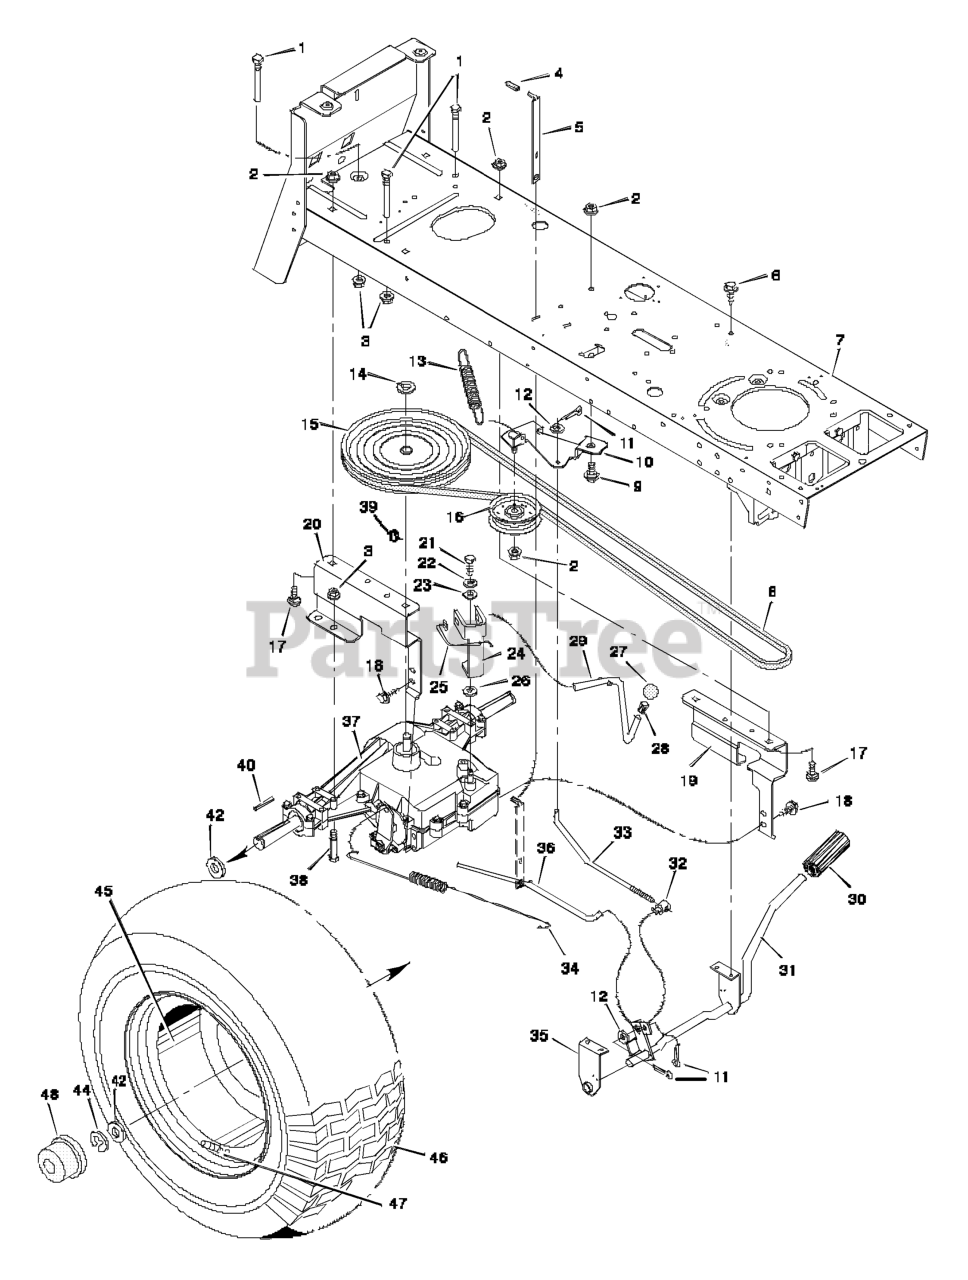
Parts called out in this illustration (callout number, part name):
1	Guide, Belt
2	Locknut, Flange
3	Locknut, Flange
5	Lever, Parking Brake
8	Belt, Motion Drive
9	Bolt, Shoulder
10	Bracket Assembly, Idler
11	Pin, Cotter
12	Washer
13	Spring, Drive Extension
14	Ring, Retainer
15	Pulley, Motion Drive
16	Pulley, Backside Idler
17	Bolt, Carriage
19	Bracket, Left Transaxle
20	Bracket, Right Transaxle
21	Bolt, Hex
22	Lockwasher
24	Yoke, Shift Lever
25	Spring
27	Knob, Shift Lever
28	Ring, Tolerance
29	Lever, Shift
30	Pedal, Clutch/Brake
31	Lever Assembly, Pedal
32	Nut, Adjustable
33	Rod, Clutch
34	Spring, Brake Extension
35	Bracket, Pedal Support
36	Rod, Brake Latch
37	Transaxle, Peerless **
38	Bolt, Hex
39	Key, Woodruff No. 9
40	Key, Square
44	E- Ring
45	Wheel & Tire Assembly
46	Tire Only *
47	Valve Stem
48	Cap, Hub
